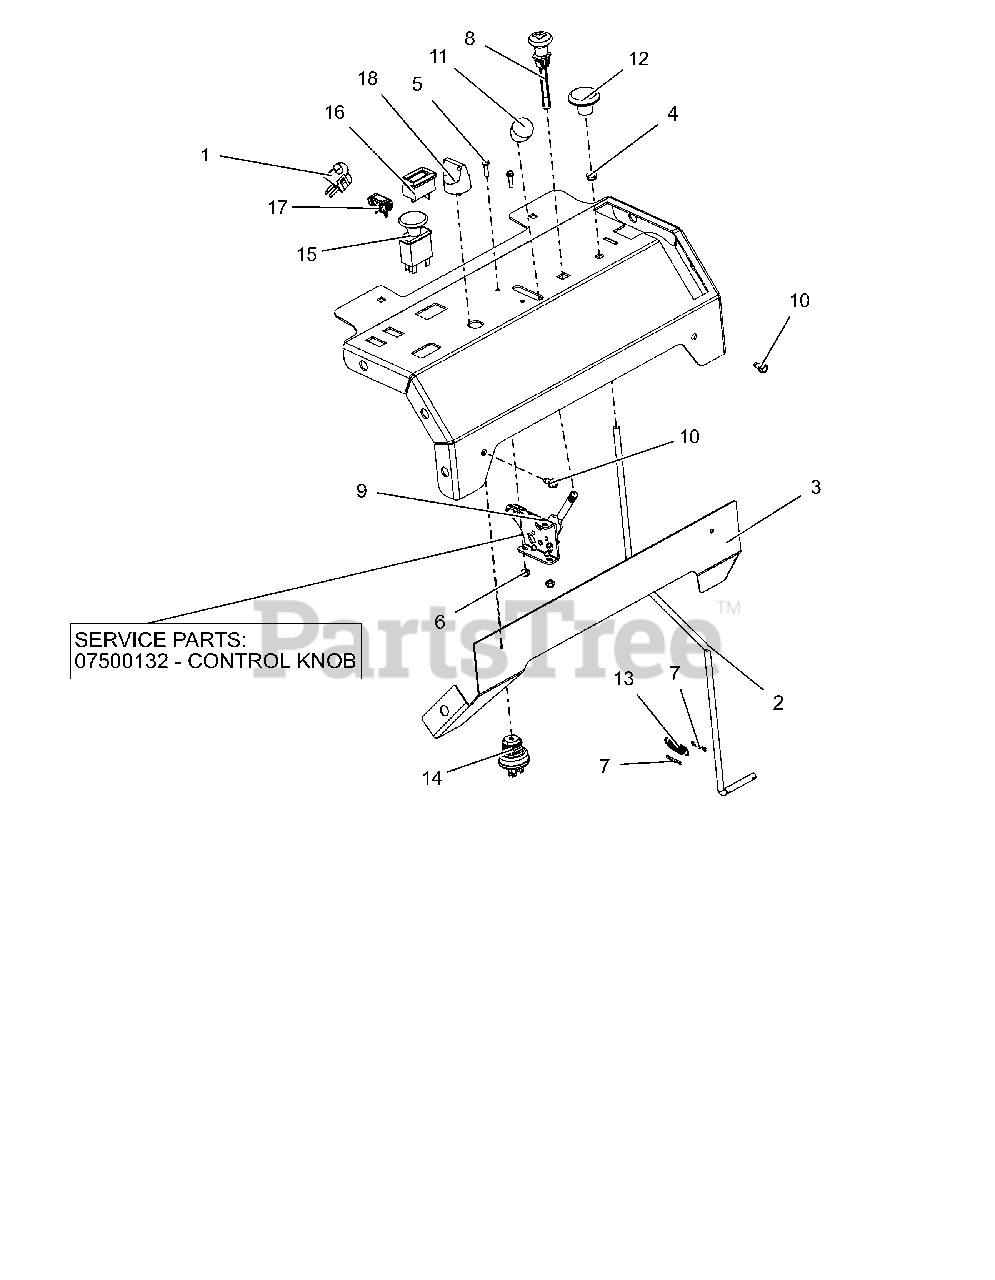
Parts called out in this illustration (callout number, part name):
1	SWITCH- SNAP MTG N.O.
2	WIREFORM, TRAILER LOCK
3	PLATE, FRONT BACKER
4	BUSHING, POLYLINER-.38 SNAPIN
5	@SCR-MCH 10-24X.75 HWH YWZC
6	@NUT-LK-NYL 10-24 W/INSRT YWZC
7	PIN-HAIR, ENDRIES #25 YWZC
8	CABLE, CHOKE (SNAP IN)
9	CABLE, PRO-CONTROL
9	KNOB-CONTROL-BLACK .38-16X.50
10	SCR-TAP .25-20X.50 HWH TR YWZ
11	KNOB-CONTROL-BLACK .38-16X.50
12	KNOB, PUSH-PULL .312-18
13	SG-TENS .048X.44X1.75 WLD 9
14	SWITCH, IGNITION
15	SWITCH, CLUTCH
16	METER, HOUR W/MAINTENANCE
17	LIGHT,INDICATOR
18	KEY, W/ SHIELD
